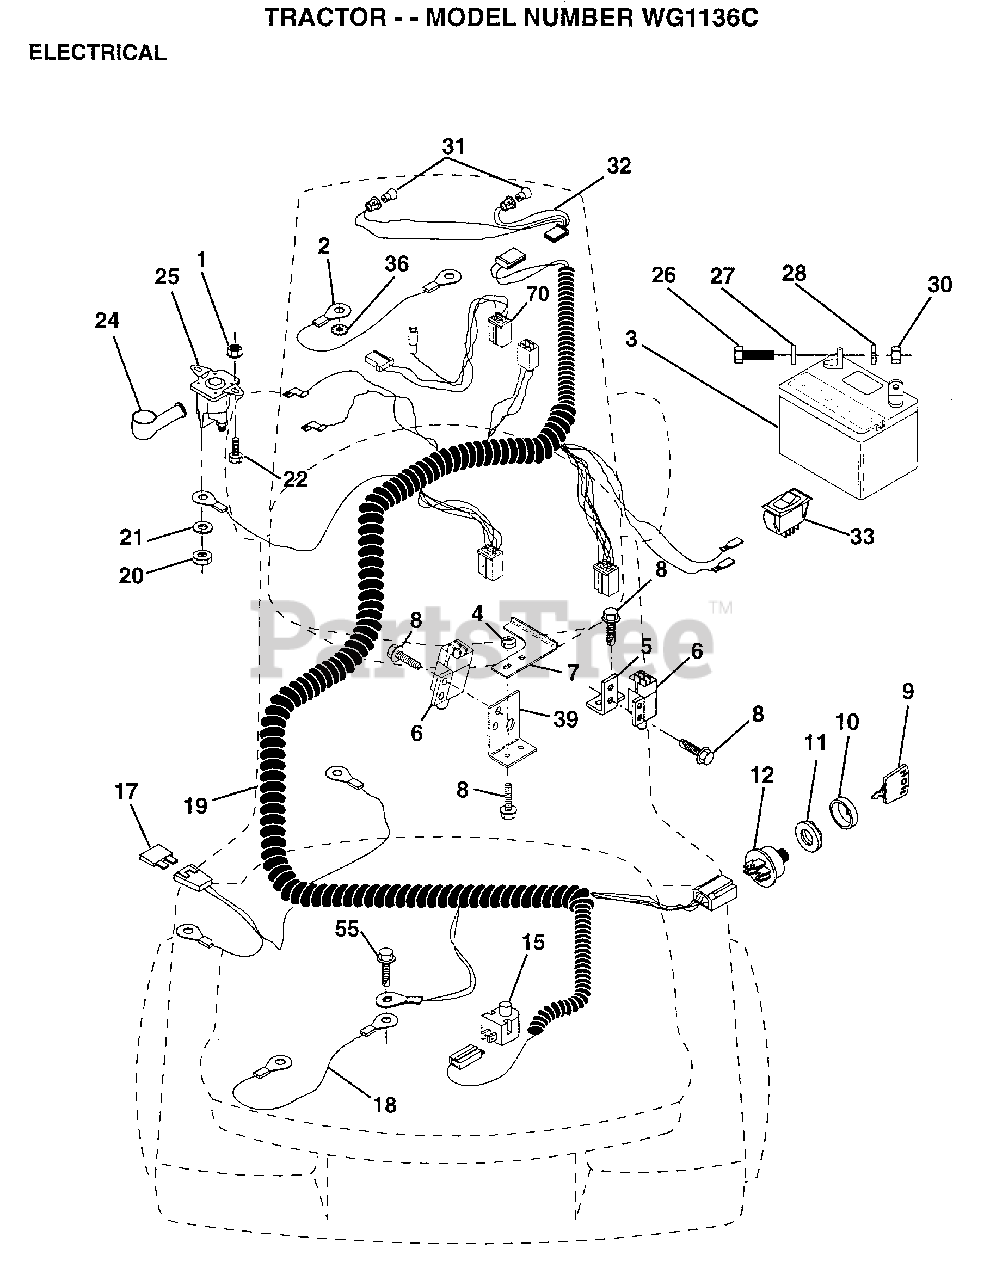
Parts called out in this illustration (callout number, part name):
1	NUT HXKEP 1/4X20
2	CABLE ASM.
4	LOCKNUT
5	BRACKET LT
6	SWITCH INTERLOCKT
7	KEEPER.ACTUAT.LR.
8	SCREW
9	KEY MLD GEN DELTA
10	COVER KEY SWITCH
15	SWITCH SEAT
17	FUSE HYT
18	CABLE ASSY
19	HARNESS.IGN.LR.
20	NUT
22	BOLT HXHD FIN
26	BOLT LT
27	WASHER
28	LOCKWASHER
31	HEADLAMP BULB
32	"HARNESS,LIGHT SOC"
33	SWITCH LT
36	LOCKWASHER
39	BRACKET SWT CLUTC
55	SCREW LT
70	HARNESS ENG DUAL
